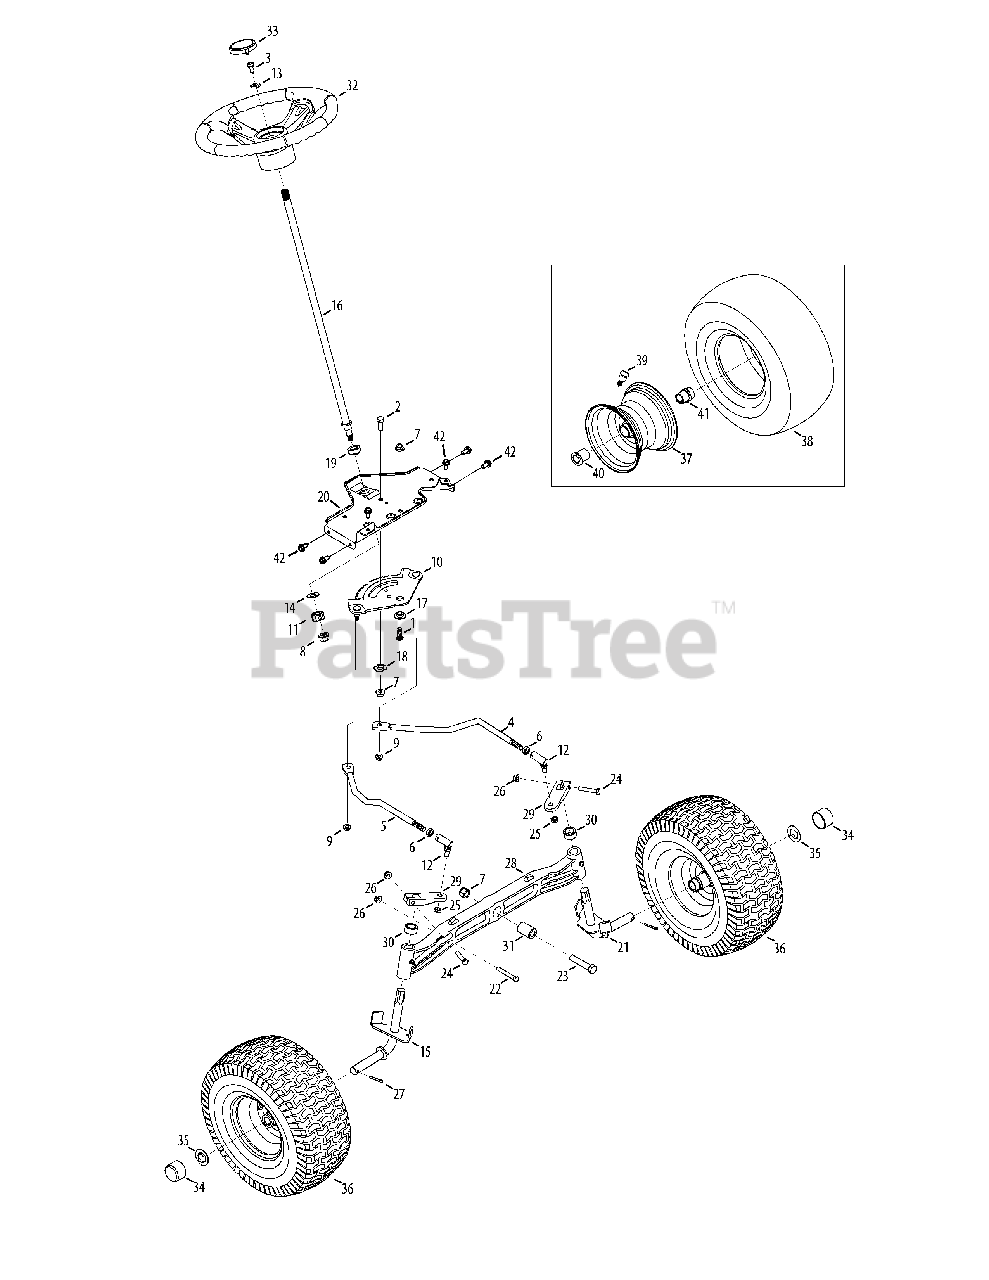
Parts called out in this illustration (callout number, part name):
1	Hex Head Screw, 3/8-16x1.00
2	Hex Head Screw, 3/8-16x1.00
3	Hex Head Screw, 5/16-18x1.00
4	LH Drag Link
5	RH Drag Link
6	Jam Nut, 7/16-20
7	Flangelock Nut, 3/8-16
8	Flangelock Nut, 7/16-20
9	Flangelock Nut, 5/16-18
10	Steering Gear
11	Steering Pinion Gear
12	Ball Joint, 7/16-20
13	Flat Washer, .406 x .875 x .105
14	Flat Washer, .51 x 1.12 x .06:HT
15	RH Axle Assembly
16	Steering Shaft, .625 OD x 24.25 LG
17	Shoulder Spacer, .385X 1.25 x .3025
18	Spacer, .38 x 1.375
19	Hex Flange Bearing 5/8 PM
20	Steering Support Bracket
21	LH Axle Assembly
22	Hex Head Screw, 5/16-18x2.25
23	Hex Head Screw, 3/8-16x2.50
24	Hex Head Screw, 5/16-18x1.75
25	Hexlock Nut, 3/8-24
26	Flangelock Nut, 5/16-18
27	Cotter Pin, 5/32x1.25
28	Pivot Bar Axle
29	Steering Block
30	Spacer, .71 ID x .125 OD x .56LG
31	Spacer, .385 x 1.00 x 1.5075
32	Steering Wheel, 5 Style
33	Steering Wheel Cap, 5 Style
34	Bumper Cap
35	Flat Washer, .781ID x 1.590OD
36	Wheel Assembly, 5 Style
37	Rim Assembly, 5 Style
38	Tire, 5 Style
39	Tubeless Air Valve
40	Flange Bearing, .760 x 1.00 x 1.20LG
41	Flange Bearing, .760ID
42	Screw, Self-tapping, 5/16-18, .750,
